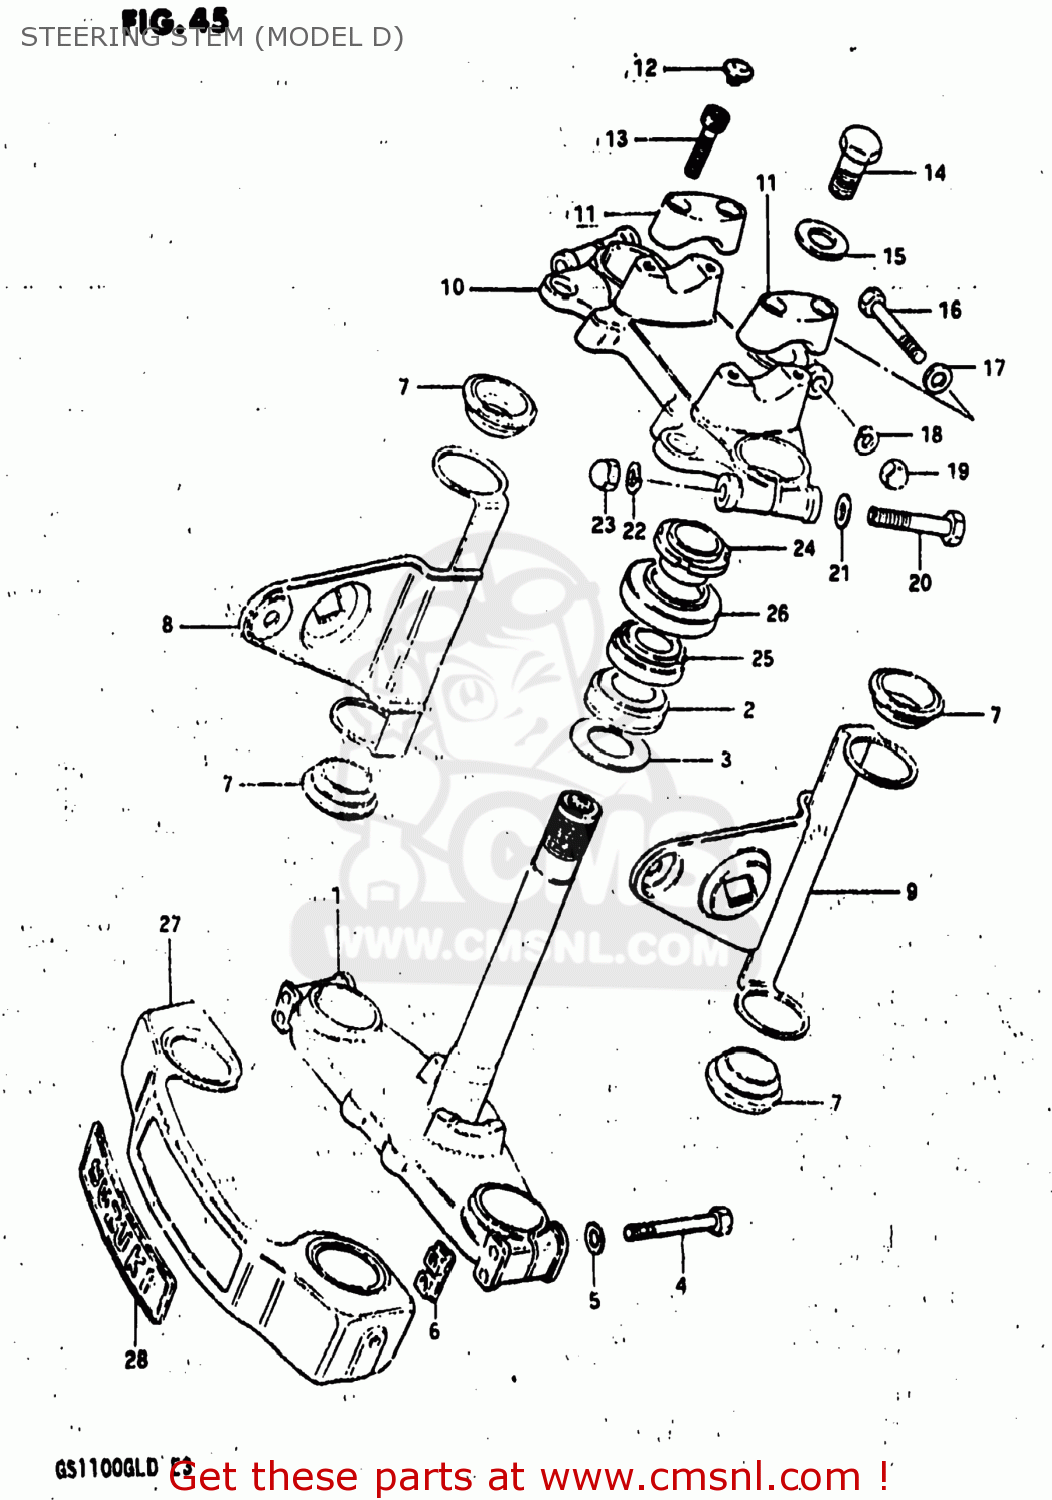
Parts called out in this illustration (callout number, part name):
1	STEM,STEERING
2	BEARING
3	WASHER
4	BOLT 8X55
5	WASHER
6	NUT,FR FORK INNER TUBE
7	CUSHION,HEADLAMP BRACKET
8	BRACKET,HEADLAMP,RIGHT
9	BRACKET,HEADLAMP,LEFT
10	HEAD,STEERING STEM
11	HOLDER,HANDLEBAR
12	CAP(OD:14.5)
13	BOLT
14	NUT,STEM HEAD
15	WASHER,STEERING STEM
16	BOLT 8X50
17	WASHER
18	WASHER,LOCK,8.
19	NUT
20	BOLT 10X55
21	WASHER
22	LOCK WASHER
23	NUT, LOWER LH
24	NUT,STEERING STEM
25	TAPER,ROLLER BEARING
26	DUST SEAL,STEERING UPR
27	COVER,FRONT FORK
28	EMBLEM,FRONT FORK COVER
